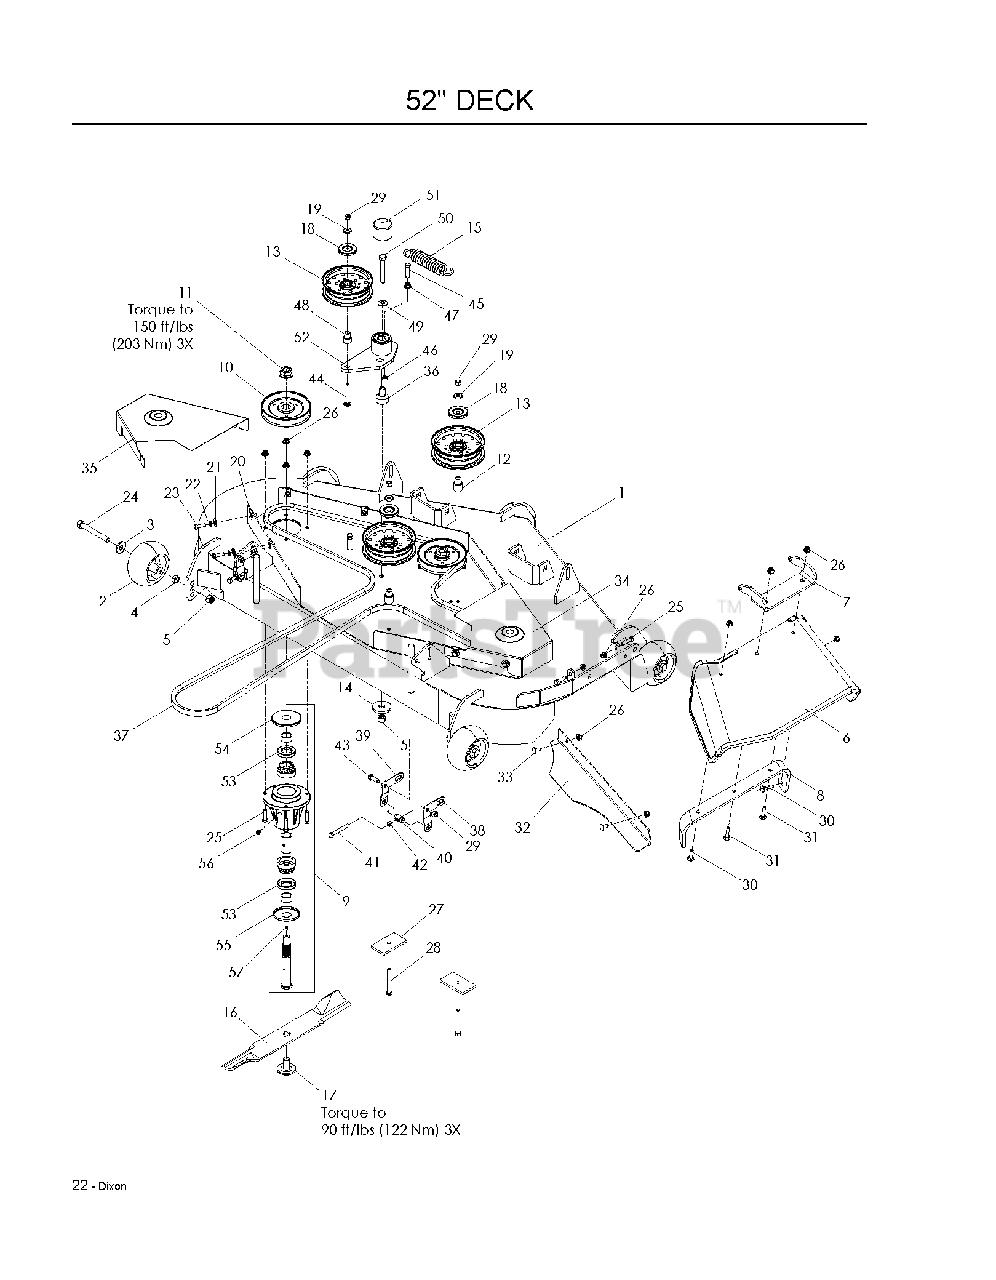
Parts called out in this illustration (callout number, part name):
1	DECK W/DECALS 52 DIX
2	GAUGE WHEEL
3	WASH USS FLAT 1/2
4	NUT 1/2 HEX JAM
5	NUT 1/2-13 HEX NYLOC ZD
6	CHUTE, RUBBER DISCHARGE 52/61"
7	PIVOT BRACKET - CHUTE
8	BRKT, REINF - CHUTE 52/61"
9	HOUSING ASM, 52/61
10	PULLEY 52
11	NUT FLANGE 3/4-16
12	IDLER BUSHING
13	IDLER PULLEY
14	WASHER, SUPPORT
16	BLADE, 18"
17	BLADE BOLT/WASHER
18	DUST SHIELD
19	WASHER, 3/8 THICK
20	U-CLIP 5/16-18 NUT RETAINER
21	WASHER 5/16 FLAT
22	WASHER 5/16 LOCK
23	HCS 5/16C X 1
24	HCS 1/2-13 X 4 GR 5 ZD
25	HCS 5/16C X 1 1/4
26	5/16-18 NYLOC FLANGE NUT
27	SUPPORT PLATE
28	HCS 3/8C X 3
29	NUT 3/8-16 NYLOC
30	BOLT, CARRIAGE 5/16X1-1/4
31	RHSNB 5/16-18 X 1-1/2 GR 5 ZD
32	CONFINEMENT PLATE, 52"
33	CARRIAGE BOLT 5/16C X 5/8"
34	SHIELD, BELT, 52 RT, BLUE
35	SHIELD.BELT.52 LT.BLUE.DIXON
36	PIVOT, BEARING
37	BELT, DECK 52"
38	PITCH, ADJUST, RT
39	PITCH, ADJUST, LT
40	TRUNION, PITCH
41	HCS 5/16-18 X 2 1/2 TPBLT
42	NUT 5/16C HEX
43	HCS 3/8C X 1
44	RHSNB 3/8-16 X 2.75
45	HCS 3/8-16 X 1-1/2
46	NUT 3/8-16 HEX JAM
47	NUT 3/8C WHIZ
48	BUSHING, IDLER
49	CONTACT BELLSPR 1/2
50	HCS 1/2C X 3 1/4
51	CAP, VINYL
52	ARM-IDLER W/BRG
53	SHAFT SEAL
54	TOP DUST CAP
55	BOTTOM DUST CAP
56	PLUG-VENTED
